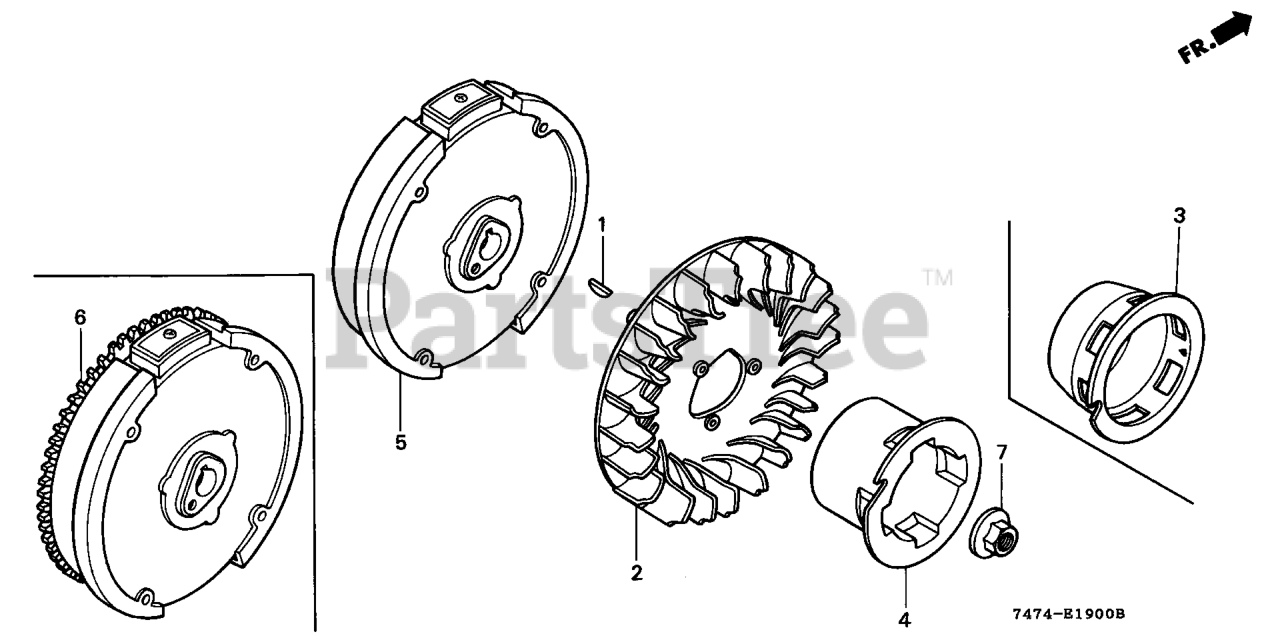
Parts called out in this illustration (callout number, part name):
1	KEY, SPECIAL WOODRUFF (25X18)
2	FAN, COOLING
4	PULLEY, STARTER
6	FLYWHEEL (STARTER MOTOR)
7	NUT, SPECIAL (14MM)
